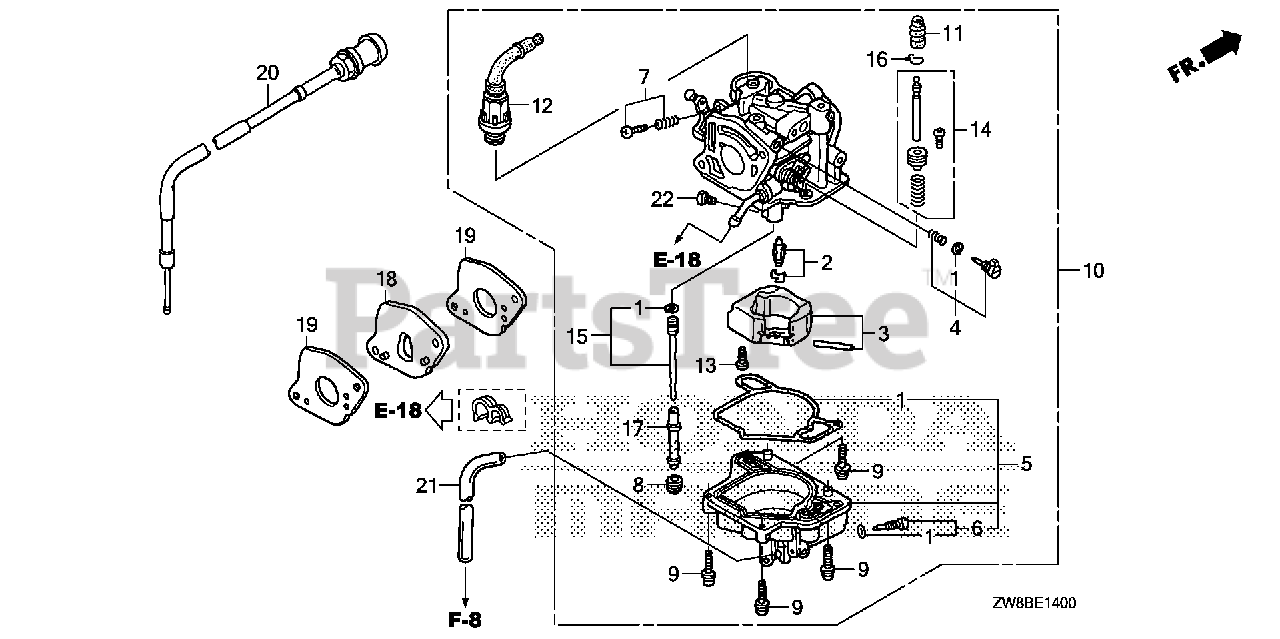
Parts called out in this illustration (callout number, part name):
1	GASKET SET
2	VALVE SET, FLOAT
5	CHAMBER SET, FLOAT
6	SCREW SET, DRAIN (CARBURETOR NO.)
7	SCREW SET
8	SCREW, PLUG
9	SCREW-WASHER
10	CARBURETOR ASSY. (BJ02A D)
12	VALVE SET, STARTER
13	SCREW, PAN
14	PLUNGER SET, ACCELERATOR PUMP
15	JET SET (#45)
16	CLIP, TUBE
17	NOZZLE, MAIN
18	INSULATOR, CARBURETOR
19	GASKET, CARBURETOR
20	CABLE, CHOKE
21	BULK HOSE, VINYL (4X7X8000) (95003-07(95003-07001-60M) (CARBURETOR NO.)
22	JET, MAIN (#98)
22	JET, MAIN (#102)
22	JET, MAIN (#105)
22	JET, MAIN (#108)
